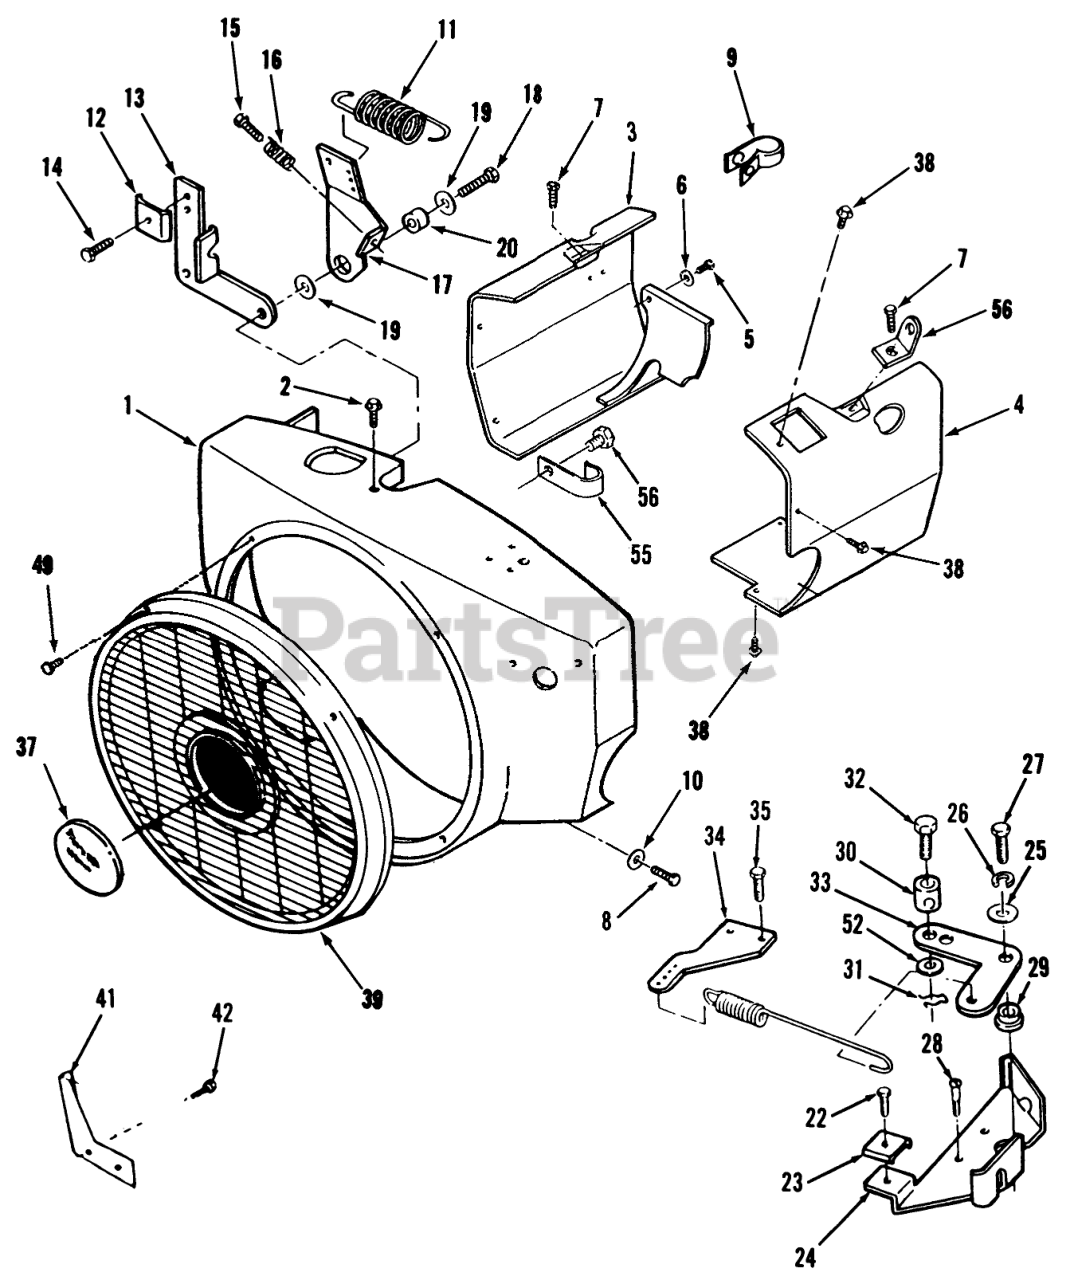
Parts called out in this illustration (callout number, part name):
1	BLOWER-HOUSING
2	HEX HD CAPSCREW
3	CYLINDER AIR HSG L H
4	Cylinder Air Housing
5	SCREW-HH
6	Clip
7	Bolt
8	Bolt
9	Clamp
10	WASHER-FLAT
11	SPRING
13	BRACKET
14	Bolt
15	SCREW-TAP
16	SPRING
17	GOVERNOR-CONT ARM
18	SCREW-HWH
19	WASHER-FLAT
20	BUSHING
22	TAPPING HEX HD CS
24	BRKT-GOVERNOR CONTRL
25	WASHER-FLAT
26	Washer-Lock
27	Bolt
28	HEX HD CAP SCREW
29	BUSHING-GOV CONTROL
31	PIN-COTTER
32	Bolt
33	LINK-GOV CONTROL
34	ADAPTER-GOV ARM
35	SCREW-TAPPING PAN HD
37	SCREW-HWH
38	Bolt
39	STATIONARY-GUARD
41	BRACKET
42	SCREW-HWH
49	Screw 1/4-20 x 3/8
55	Clip
56	Bracket-Lifting
